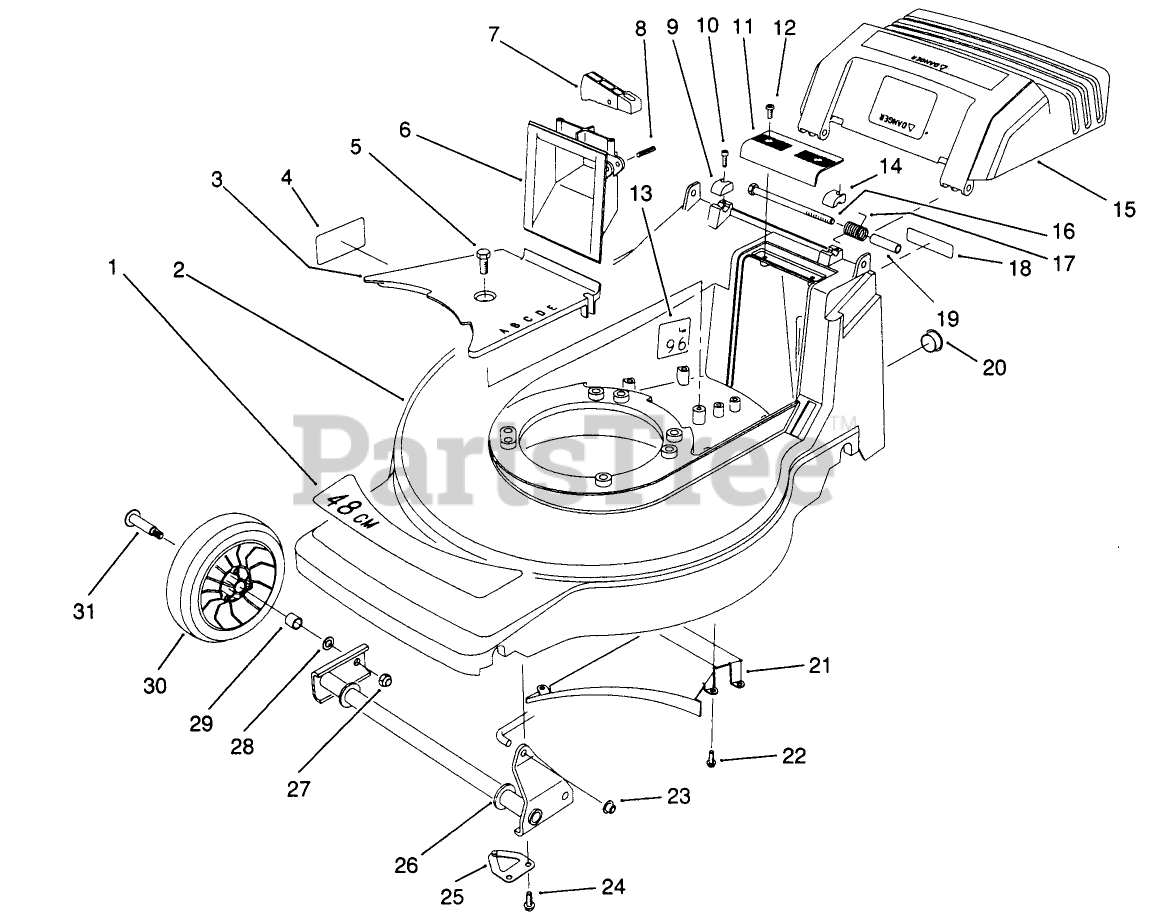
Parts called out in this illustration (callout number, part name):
5	SCREW-HWHTF
6	GRIP - LOWER
7	TRIGGER - HOC
9	CAP-HINGE BOLT, RH
10	SCREW-HSH
11	GRIP-UPPER
12	SCREW-PPH, PLASTITE
14	CAP-HINGE BOLT, LH
15	HP DISCHARGE DOOR
16	SCREW-HH
19	SPACER-DOOR
22	SCREW-HWHTF
23	NUT-PUSH
26	FRONT PIVOT WA
28	WASHER
29	BUSHING
31	BOLT-WHEEL
